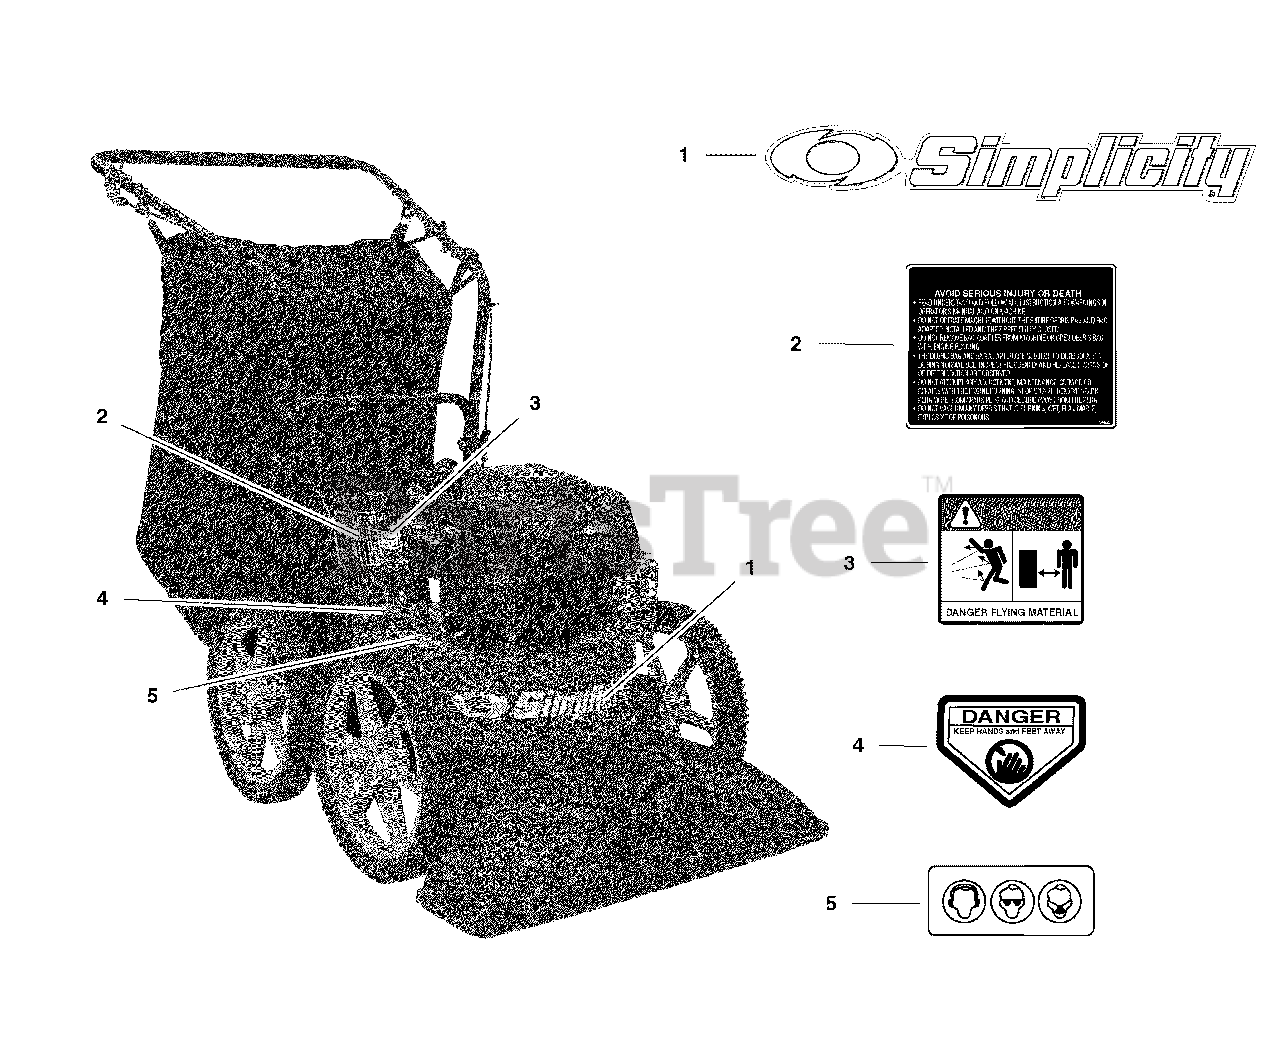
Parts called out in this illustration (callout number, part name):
1	DECAL, Simplicity
1	DECAL, Snapper
2	DECAL, Danger, Cut Finger
3	DECAL, Thrown Objects
4	DECAL, Personal Protection
5	DECAL, Warning, Vacuum
